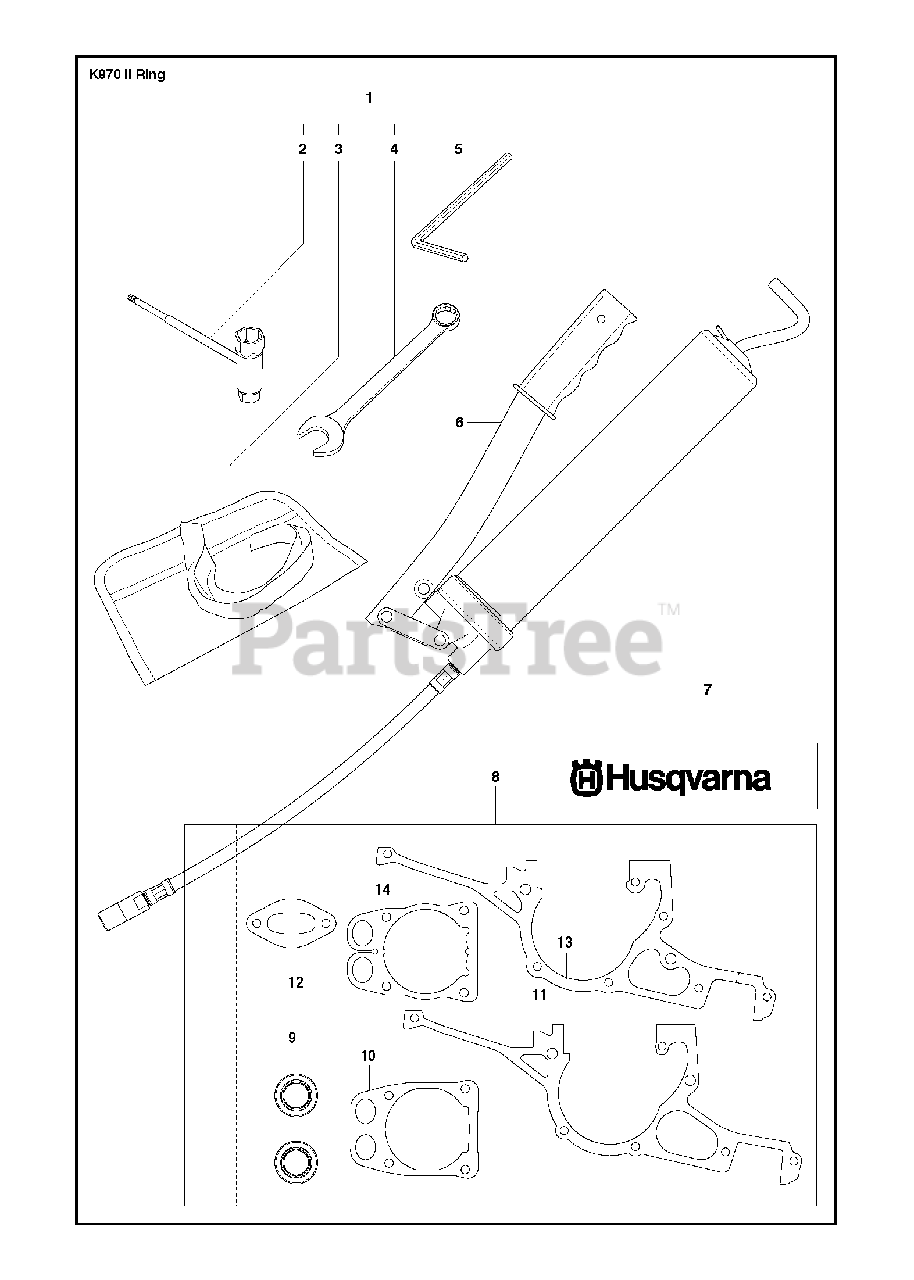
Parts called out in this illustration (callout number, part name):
7	GREASE
8	GASKET KITIncl. 9 - 14
9	SEALING RING
12	GASKET
